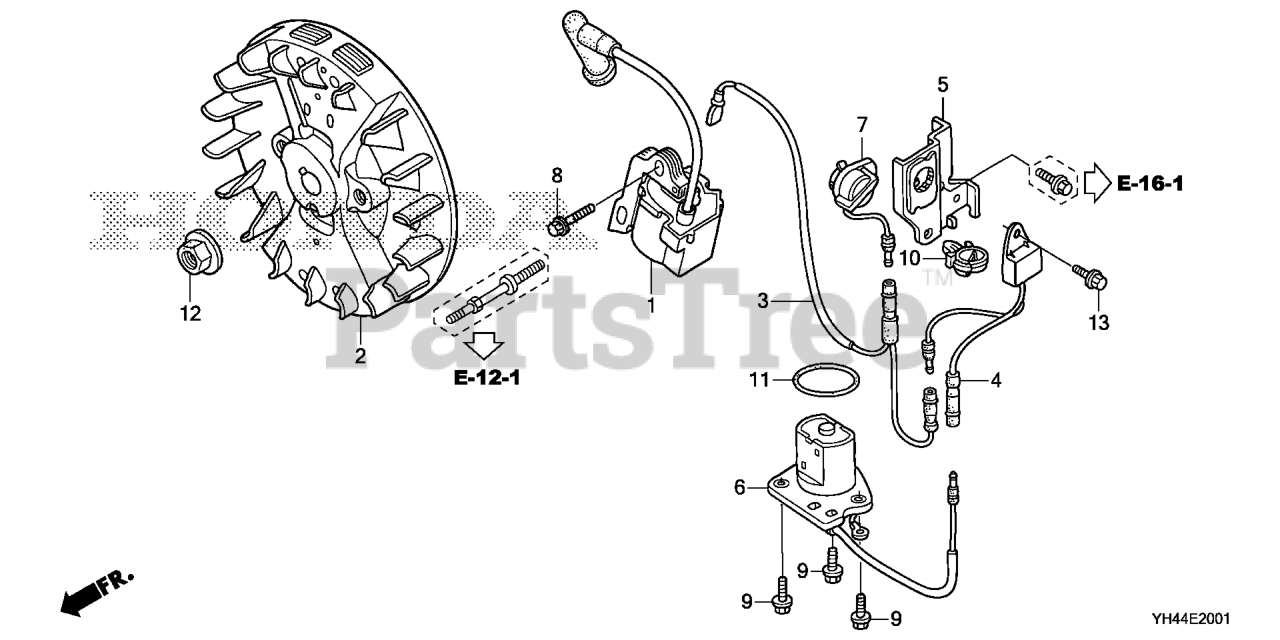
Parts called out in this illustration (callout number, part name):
1	COIL ASSY., IGNITION
3	WIRE, STOP SWITCH
4	ALERT UNIT, OIL (CHONGQING LIHUA)
4	ALERT UNIT, OIL
5	BRACKET, STOP SWITCH
6	SWITCH ASSY., OIL LEVEL
7	SWITCH ASSY., ENGINE STOP Use from Engine SN 2092216 to 2359126.
8	BOLT, FLANGE (5X20)
9	BOLT, FLANGE (5X14)
10	CLIP, WIRE HARNESS
11	O-RING (34.6X2.5)
12	NUT, FLANGE (10MM)
13	BOLT, FLANGE (6X8)
